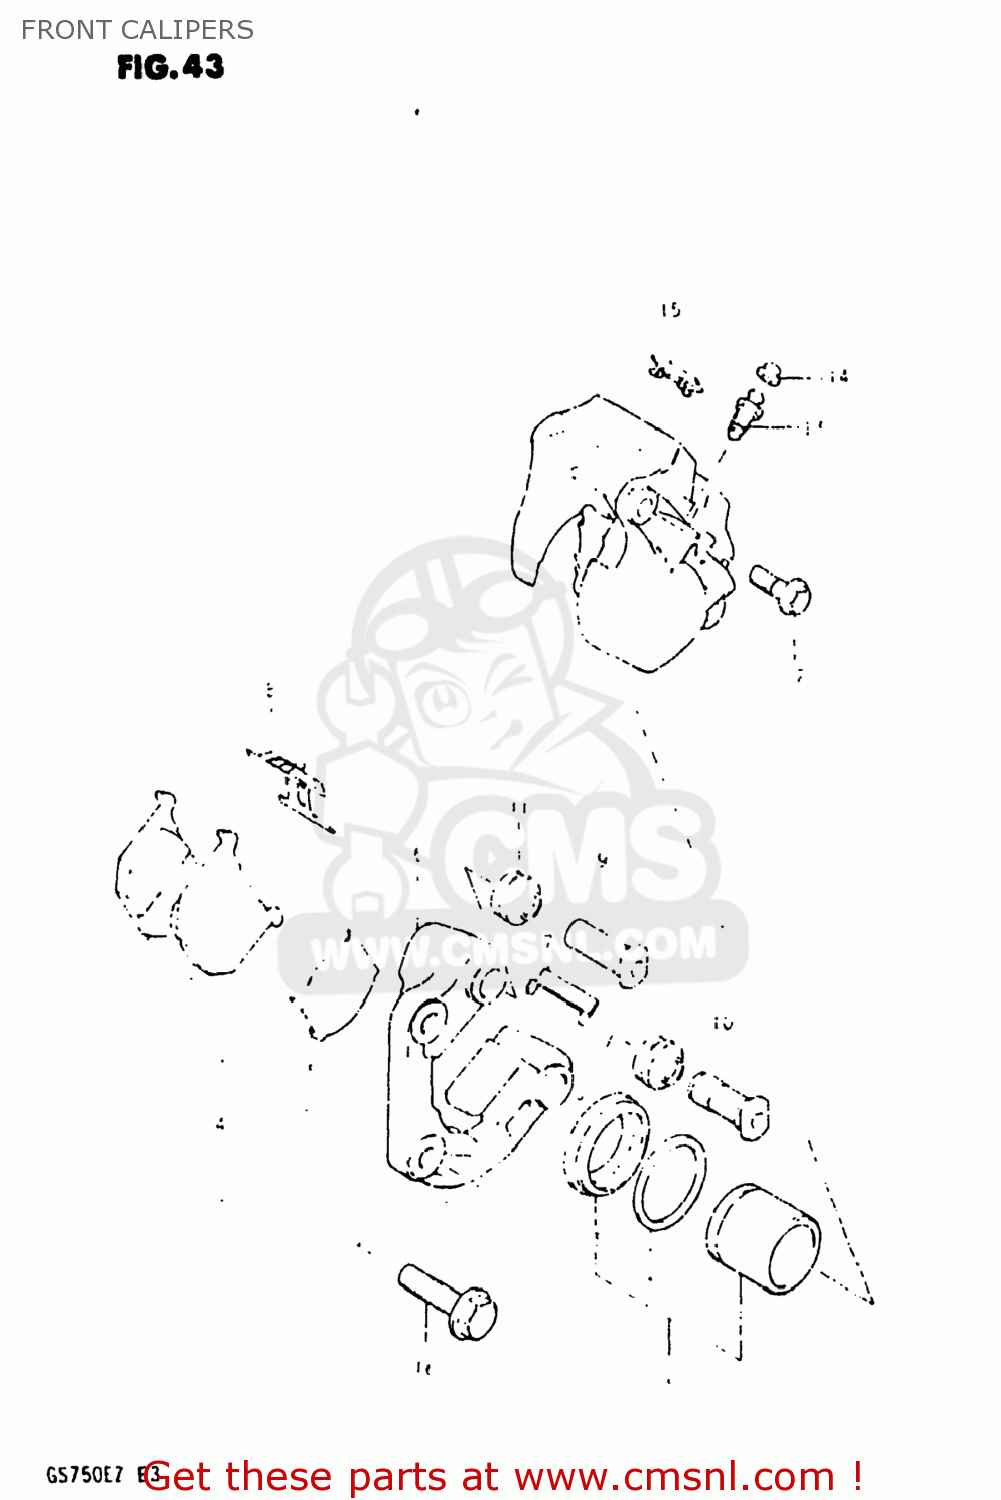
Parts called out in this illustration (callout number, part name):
0	CALIPERS ASSY, FRONT RH
1	PISTON SET
2	SEAL,PISTON
3	BOOT,PISTON
4	PAD SET (MCA)
5	SHIM,PAD
6	CARRIER,CALIPER,LEFT
7	GUIDE,PAD
8	SPRING,PAD
9	AXLE NO.1
10	AXLE NO.2
11	BOOT,AXLE
12	BOLT,CALIPER HOUSING
13	BLEEDER
14	CAP,BREATHER
15	COVER,INDICATOR
16	BOLT 10X37
